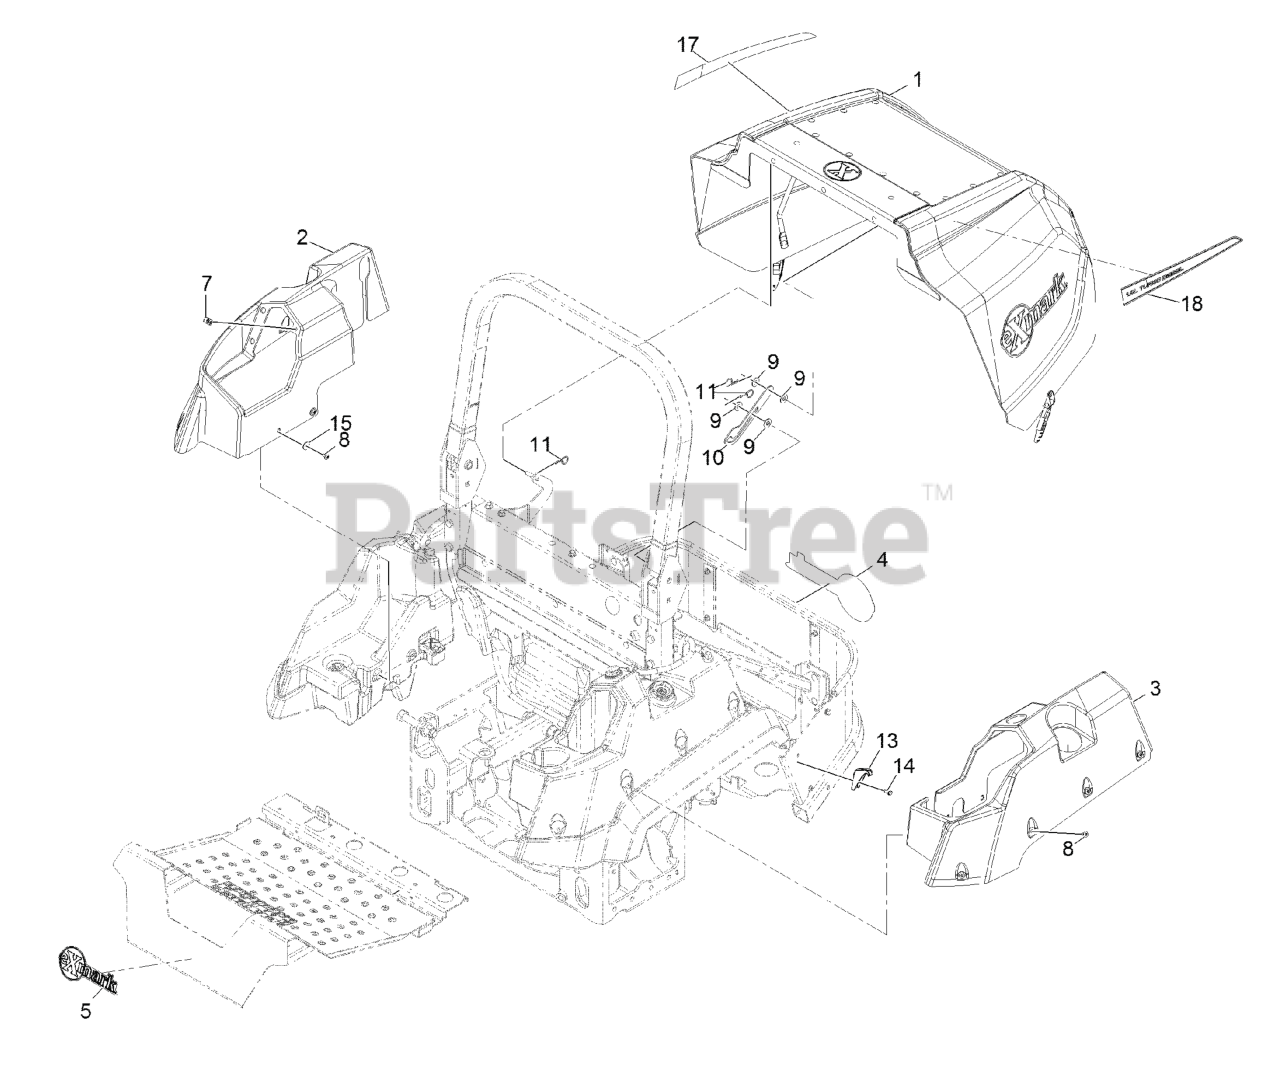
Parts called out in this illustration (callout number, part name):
1	Hood ASM
2	COVER-TANK, RH
3	COVER-TANK, LH
4	DECAL-EXMARK
5	DECAL-EXMARK
8	SCREW-TORX
9	WASHER-FLAT
10	PROP-HOOD
11	PIN-COTTER, HAIR
13	LATCH-CATCH
14	SCREW-HWH
15	WASHER-FLAT
17	DECAL-TURBO DIESEL-RH
18	DECAL-TURBO DIESEL-LH
